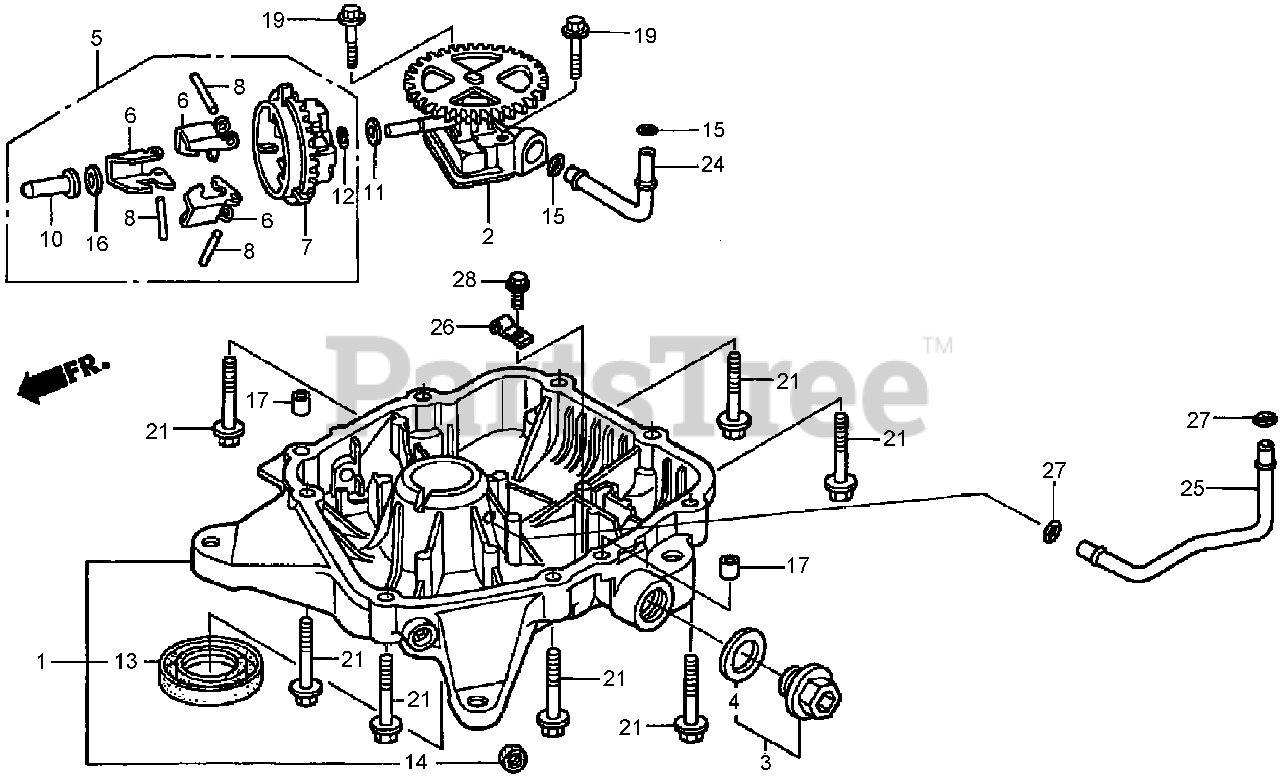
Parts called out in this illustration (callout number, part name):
1	OIL PAN ASM
2	OIL PUMP ASM
3	DRAIN CAP ASM
4	GASKET-CAP, OIL FILLER
5	GOVERNOR ASM
6	WEIGHT-GOVERNOR
7	HOLDER-WEIGHT, GOVERNOR
8	PIN-WEIGHT, GOVERNOR
10	SLIDER-GOVERNOR
11	WASHER (6X16)
12	CLIP-HOLDER, GOVERNOR
13	SEAL-OIL (31X50X8)
14	SEAL-OIL (10X16X4.5)
15	O-RING (7.5X2.3)
16	WASHER-PLAIN (6MM)
17	Pin-Dowel (8X14)
19	BOLT-FLANGE (6X35)
21	BOLT-FLANGE (8X40)
24	PIPE-PUMP, OIL
25	PIPE-SUPPLY, OIL
26	HOLDER-PIPE, OIL
27	O-RING (5.8X2)
28	BOLT-FLANGE (6X12)
